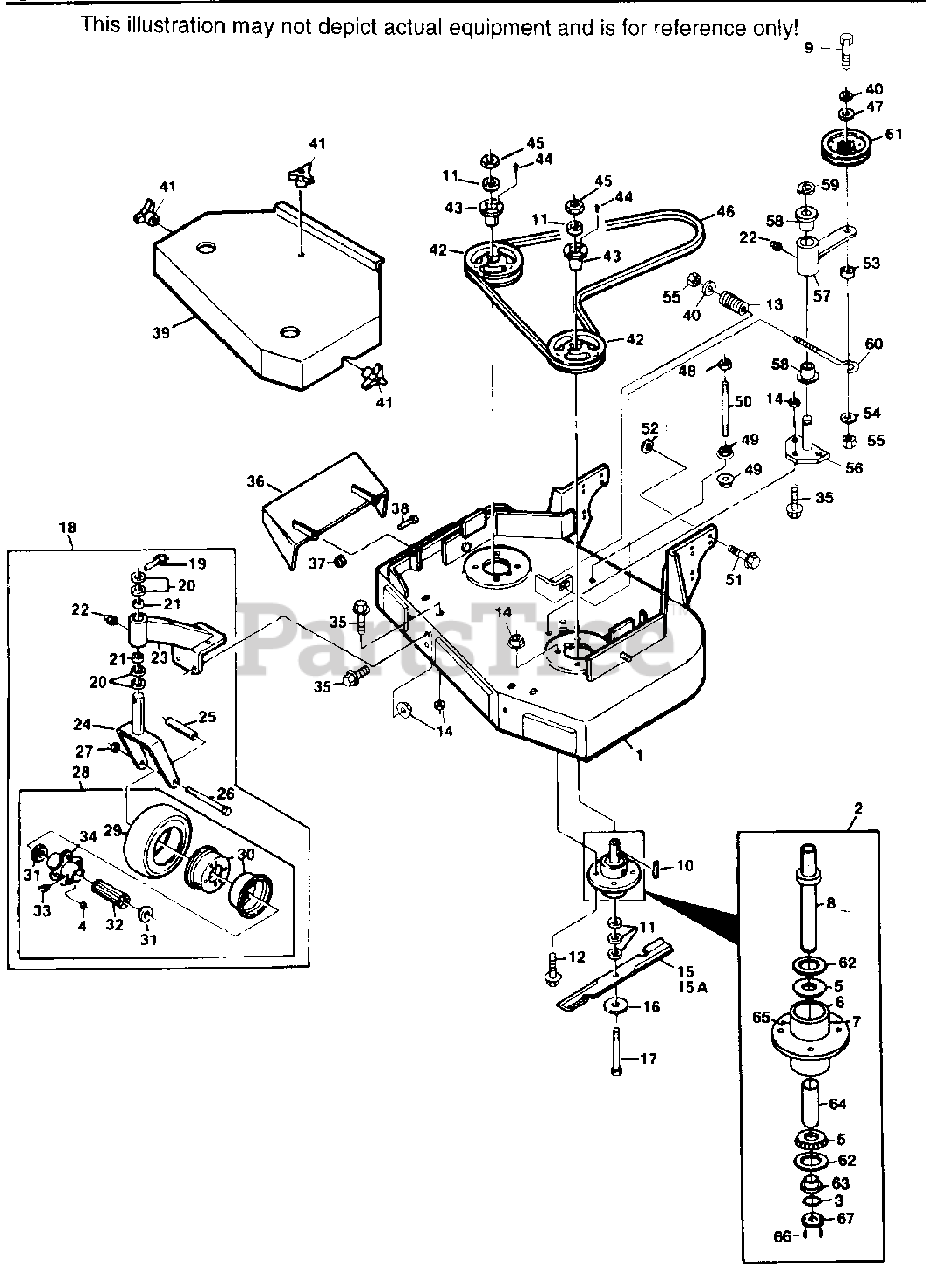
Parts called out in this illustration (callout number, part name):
1	CUTTER DECK(INCLUDES DECALS)
2	CUTTER SPINDLE ASSY.
3	RETAINING RING, 1" EXT.-INVERTED
4	TAPERED NUT, 5/16-24
5	TAPERED BEARING
6	SPINDLE HOUSING
7	GREASE FITTING, STR., 5/16 SERRATED
8	SPINDLE SHAFT
10	KEY, 1/4 X 1/4 X 2"
11	SPACER, CUTTER BLADE - SMALL
12	CAPSCREW, 5/16-18 X 1-1/4" SERRATED FLANGE
13	SPRING, CUTTER DECK
14	NUT 5/16-18 SERRATED FLANGE
15	CUTTER BLADE 16-1/2"
15A	CUTTER BLADE 16 1/2 HIGH LIFT
16	FLATWASHER, 5/8 W
17	HEX HD. BOLT, 5/8-11 X 9-1/2"
18	CASTER ASSEMBLY(INCLUDES 19-28)
19	QUICK PIN
20	SPACER, CASTER YOKE, 1/2" LONG
21	BRONZE BEARING
22	GREASE ZERK
23	SUPPORT ASSEMBLY(INCLUDES 21-23)
24	CASTER YOKE
25	SLEEVE, CASTER WHEEL BEARING
26	HEX HD. BOLT, 1/2-13 X 5-1/2"
27	ELASTIC STOP NUT, 1/2-13
28	WHEEL ASSY.(INCLUDES 4,29-34)
29	TIRE ONLY CASTER WHEEL
30	RIM PAIR, CASTER WHEEL
31	RETAINER, BEARING, CASTER WHEEL
32	ROLLER BEARING, CASTER WHEEL
33	GREASE FITTING, 45 DEGREE 1/4-28
34	HUB ASSEMBLY
35	CAPSCREW, 5/16-18 X 3/4" SERRATED FLANGE
36	DISCHARGE CHUTE
37	HEX NUT, 5/16-18 ELASTIC STOP
40	FLAT WASHER, 3/8" SPECIAL
41	WING NUT, 3/8-16
42	PULLEY
43	TAPERED HUB
46A	BELT, BLADE DRIVE
47	SPACER
49	NUT, 3/8-16 SERR FLANGE
50	SUPPORT, BELT COVER
51	CAPSCREW, 7/16-14 X 1" SERR FLANGE HH
52	NUT, 7/16-14 SERR FLANGE
53	SPACER, J-HOOK
54	WASHER, 3/8 X 1-1/2 X 16 GA
55	ELASTIC STOP NUT, 3/8-16
56	IDLER PIVOT
57	IDLER ARM ASSY.(INCLUDES 22 & 58)
58	BRONZE BEARING
59	RETAINING RING, 1-1/8" EXT. "E"
60	J-HOOK
61	IDLER PULLEY, BELT CLUTCH
62	SEAL, CUTTER SPINDLE
63	SPINDLE BUSHING
64	SLEEVE CUTTER SPINDLE
65	RELIEF FITTING, CUTTER SPINDLE
67	SPACER, LARGE
NS	INNER TUBE ONLY
